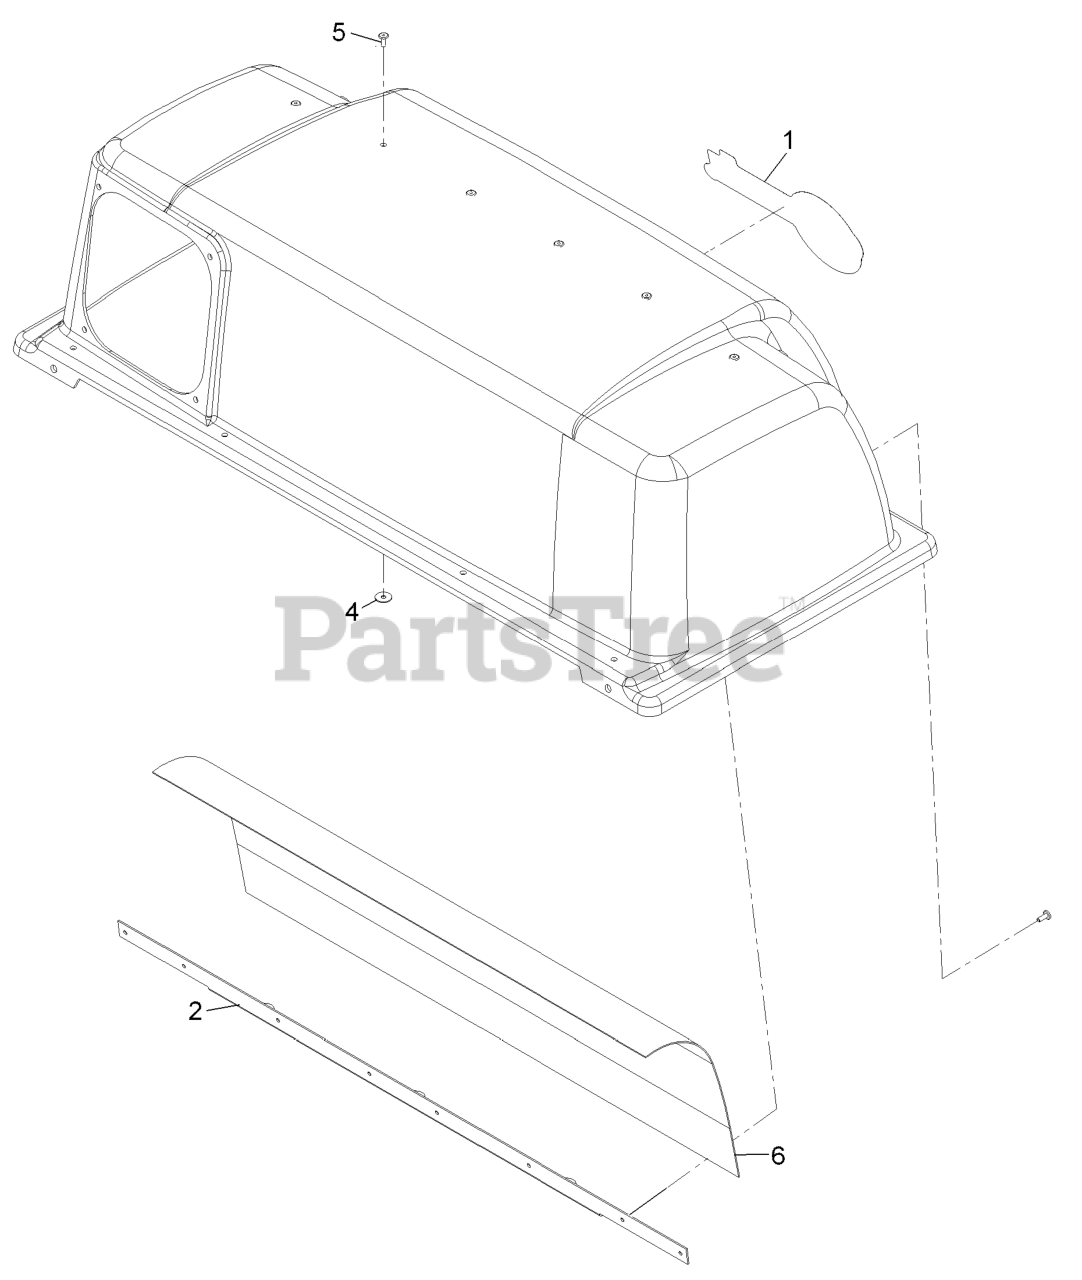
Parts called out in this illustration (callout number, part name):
1	DECAL-EXMARK LOGO
2	SUPPORT-SCREEN
4	WASHER-FLAT
5	RIVET-BLIND
6	SCREEN-BAGGER
